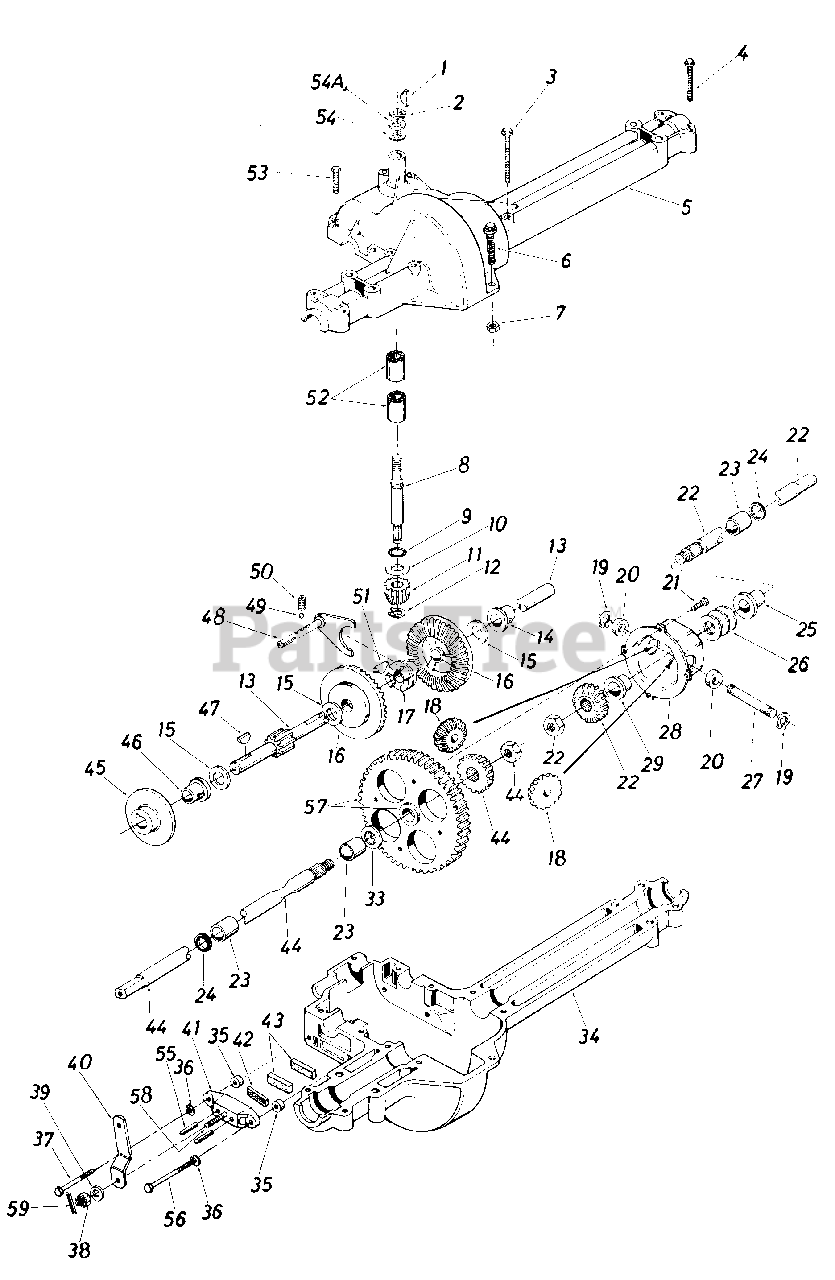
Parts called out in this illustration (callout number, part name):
1	#4 Hi-Pro Key 3/32 x 5/8" Dia.
2	Snap Ring .625" Shaft
3	Hex Bolt 1/4-20 x 1.75" Lg.
4	Hex Bolt 5/16-18 x 2.5"
5	Upper Housing
6	Hex Fl-Bolt 1/4-20 x .88" Lg.'
7	Hex Nut 1/4-20 Thd.
8	Input Shaft
9	Square Seal 5/8" I.D.
10	Thrust Washer 5/8" I.D. x 1.25" O.D.
11	Pinion Input 14T
12	Retaining Ring 7/16" Ext.
13	Drive Shaft
14	Flange Brg. 5/8" I.D. x 3/4" Lg.
15	Fl-Wash. (See Below)
16	Bevel Gear 42T
17	Clutch Collar
18	Miter Gear 15T (H.D.)
19	Snap Ring
20	Thrust Bearing 1/2" I.D. x 1.0" O.D.
21	Pan Head Scr. 1/4-20 x .50" Lg. w/Patch
22	Axle R.H. Ass'y.-Kit
23	Sleeve Bearing 3/4" I.D. x 1.0" Lg.
24	Oil Seal 3/4" I.D.
25	Flange Bearing 3/4" I.D. x 15/1 6" Lg.
26	Fl-Wash. .760" I.D. x 1.49 O.D.
27	Cross Shaft
28	Differential Housing Ass'y.
33	Fl-Wash. .760" I.D. x 1.49" O.D.
34	Lower Housing
35	Spacer .53" O.D. x 318" Lg.
36	L-Wash. 1/4" I.D.
37	Hex Bolt 1/4-20 x 1.50" Lg. (Grade 5)
38	Castle Nut 5/16-24 Thd.
39	Fl-Wash. .344" I.D. x .875" O.D.
40	Actuating Arm
41	Brake Yoke
42	Puck Plate
43	Brake Puck
44	Axle L.H. Ass'y.-Kit
45	Brake Disc
46	Flange Bearing 518" I.D. x 15/16" Lg.
47	Woodruff Key 3/16 x 5/8 HT
48	Shift Fork Ass'y.
49	Ball Detent .250" Dia.
50	Spring Detent
51	#9 Hi-Pro Key 3/16" x 3/4" Dia. HT
52	Needle Brg. 5/8" I.D. x 1/2" Lg.
53	Hex Bolt 1/4-20 x 1.00" Lg.
54	Fl-Wash. 5/8" I.D. x .030
54A	Fl-Wash. 5/8" I.D. x .040
55	Actuating Pin 5/16" Dia.
56	Hex Bolt 1/4-20 x 2.50" Lg. (Grade 5)
57	Differential Gear 72T Ass'y. w/Bearing
58	Sq. Hd. Bolt 5/16-24 Thd.
59	Cotter Pin 3/32" Dia. x .50" Lg.
